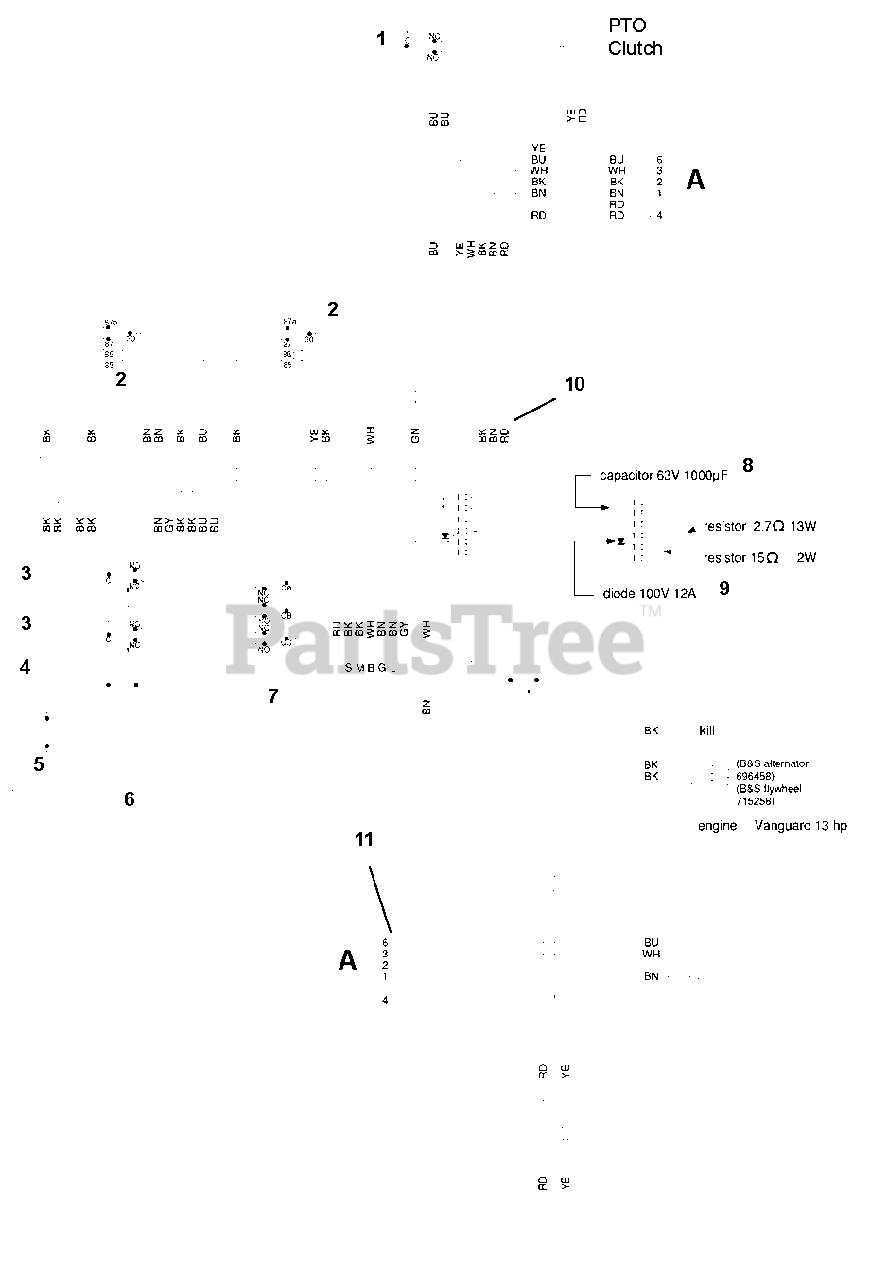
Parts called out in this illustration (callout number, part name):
5	Lever, Emergency
6	Lever, Control
7	Switch, PTO
8	Condenser
10	Cable Harness
11	Cable
